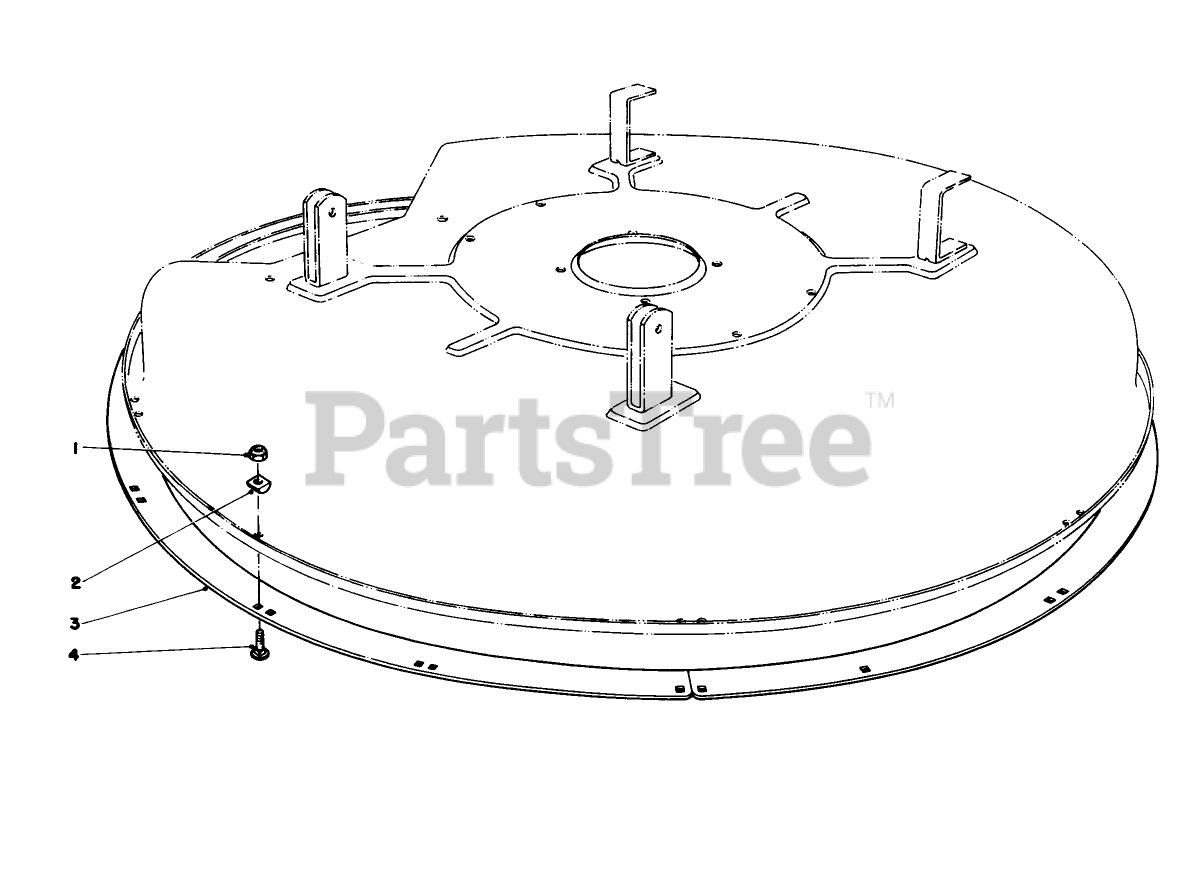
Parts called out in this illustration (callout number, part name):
1	NUT-LOCK, NI
3	DECK RING *B
4	BOLT-CARR
